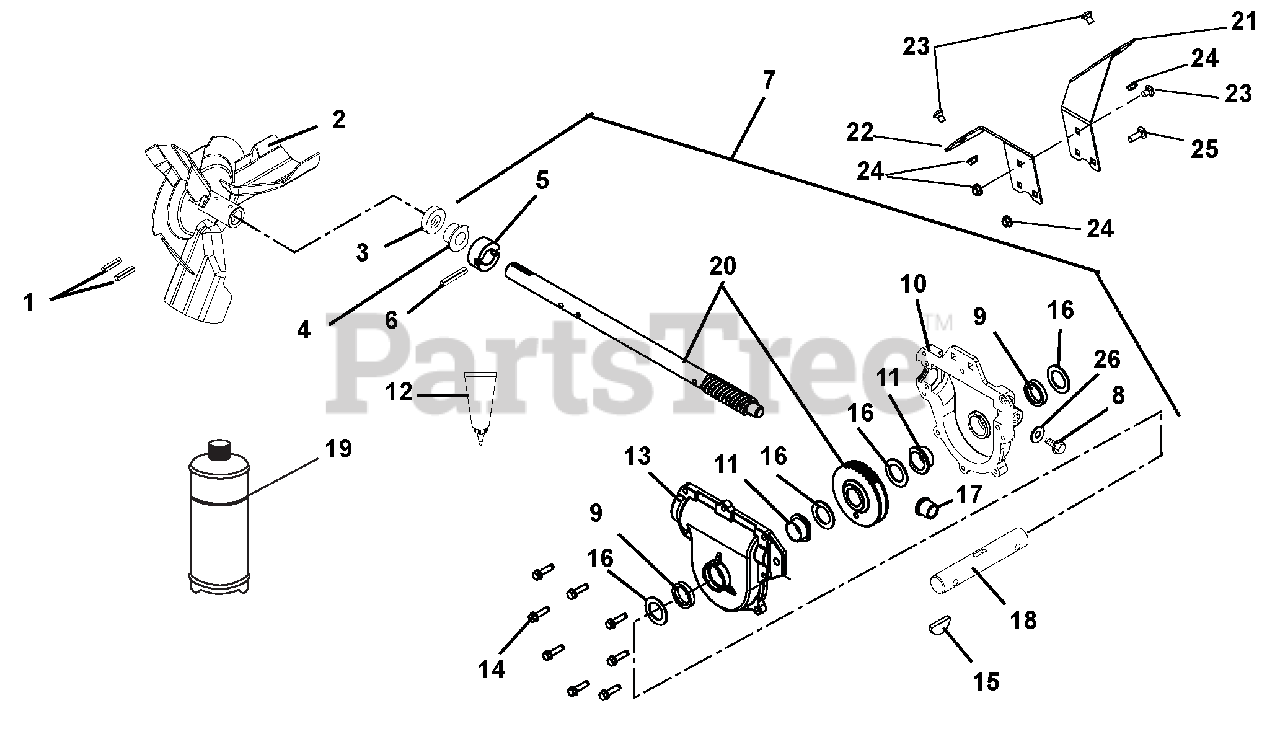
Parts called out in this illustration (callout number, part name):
1	PIN-ROLL .250X1.75
2	IMPELLER, 3 BLADE-14"
3	SEAL-OIL .875X1.375X.25 RBR OD
4	BSHG-FLG .876 X 1.500 X .750
5	THRUST COLLAR, .875" ID
6	PIN-GRV .250X1.50 TP E
7	GEAR CASE ASSEMBLY - COMMON
8	SCR-TAP .38-16X.75 ROLOK YZ WX
9	SEAL-OIL 1.000X1.375X.250
10	GEARCASE, ALUMINUM, LH
11	BSHG-FLG 1.003X1.5X.625
12	LOCTITE 518 GASKET--6ML TUBE
13	GEARCASE, ALUMINUM, RH
14	@SCR-TAP .25-20X1.00 HWH TR YZ
15	KEY-WDRF .25X.875 HRD #A
16	WSHR-FL-STL 1.010X1.505X.062YZ
17	BSHG-FLG .629 X 1.000 X .750
18	RAKE SHAFT, SHORT-COMMON
19	ARIENS 16 OZ.BOTTLE OF L2 LUBE
20	WORM SHAFT & GEAR
21	BRACKET, GEAR CASE SUPPORT-LH
22	BRACKET, GEAR CASE SUPPORT-RH
23	@BLT-RHDSSQNK .31-18X.62 G5YZ
24	@NUT-LK-TOP-FLG .31-18 YWZC
25	@BLT-RDHDSQNK .31-18X1.00 G5YZ
26	WSHR-FIBER .437X.656X.032
